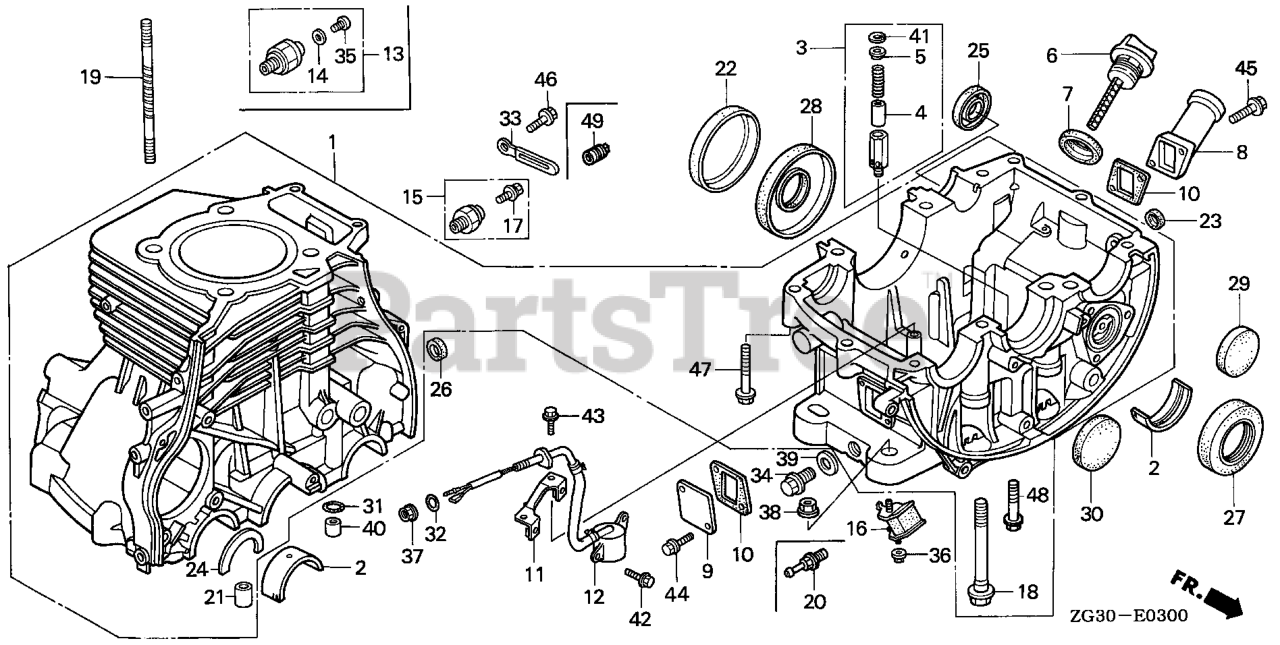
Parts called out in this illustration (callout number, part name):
1	CYLINDER ASSY. (Q-SEL)
2	BEARING A, MAIN (BLUE)
2	BEARING B, MAIN (BLACK)
2	BEARING C, MAIN (BROWN)
2	BEARING D, MAIN (GREEN)
2	BEARING E, MAIN (YELLOW)
2	BEARING F, MAIN (PINK)
2	BEARING G, MAIN (RED)
2	BEARING A, MAIN (US 0.25) (BLACK)
2	BEARING B, MAIN (US 0.25) (BROWN)
2	BEARING C, MAIN (US 0.25) (GREEN)
2	BEARING A, MAIN (US 0.75) (BLACK)
2	BEARING B, MAIN (US 0.75) (BROWN)
2	BEARING C, MAIN (US 0.75) (GREEN)
3	VALVE ASSY., RELIEF (NOT AVAILABLE)
4	VALVE, RELIEF
5	SEAT, RELIEF VALVE
6	CAP, OIL FILLER
7	GASKET, OIL FILLER CAP
8	EXTENSION, OIL FILLER
9	PLATE, EXTENSION
10	GASKET, EXTENSION OIL FILLER (NON-ASBESTOS)
18	BOLT-WASHER (11X115)
19	BOLT, STUD (10X103.5)
21	PIN, DOWEL (13X20)
23	OIL SEAL (8X14X5)
26	OIL SEAL (8X14X5)
27	OIL SEAL (40X67X10)
28	OIL SEAL (36X90X9)
30	PLUG, SEALING (52MM)
31	O-RING (9.8X1.9)
34	BOLT, DRAIN PLUG (14MM)
39	WASHER, DRAIN PLUG (14MM)
40	PIN A, DOWEL (10X16)
41	CIRCLIP (INNER) (12MM)
44	BOLT, FLANGE (6X16) Use from Engine SN 2056820.
45	BOLT, FLANGE (6X22)
47	BOLT, FLANGE (8X40) Use up to Engine SN 1003236.
48	BOLT, FLANGE (8X50)
